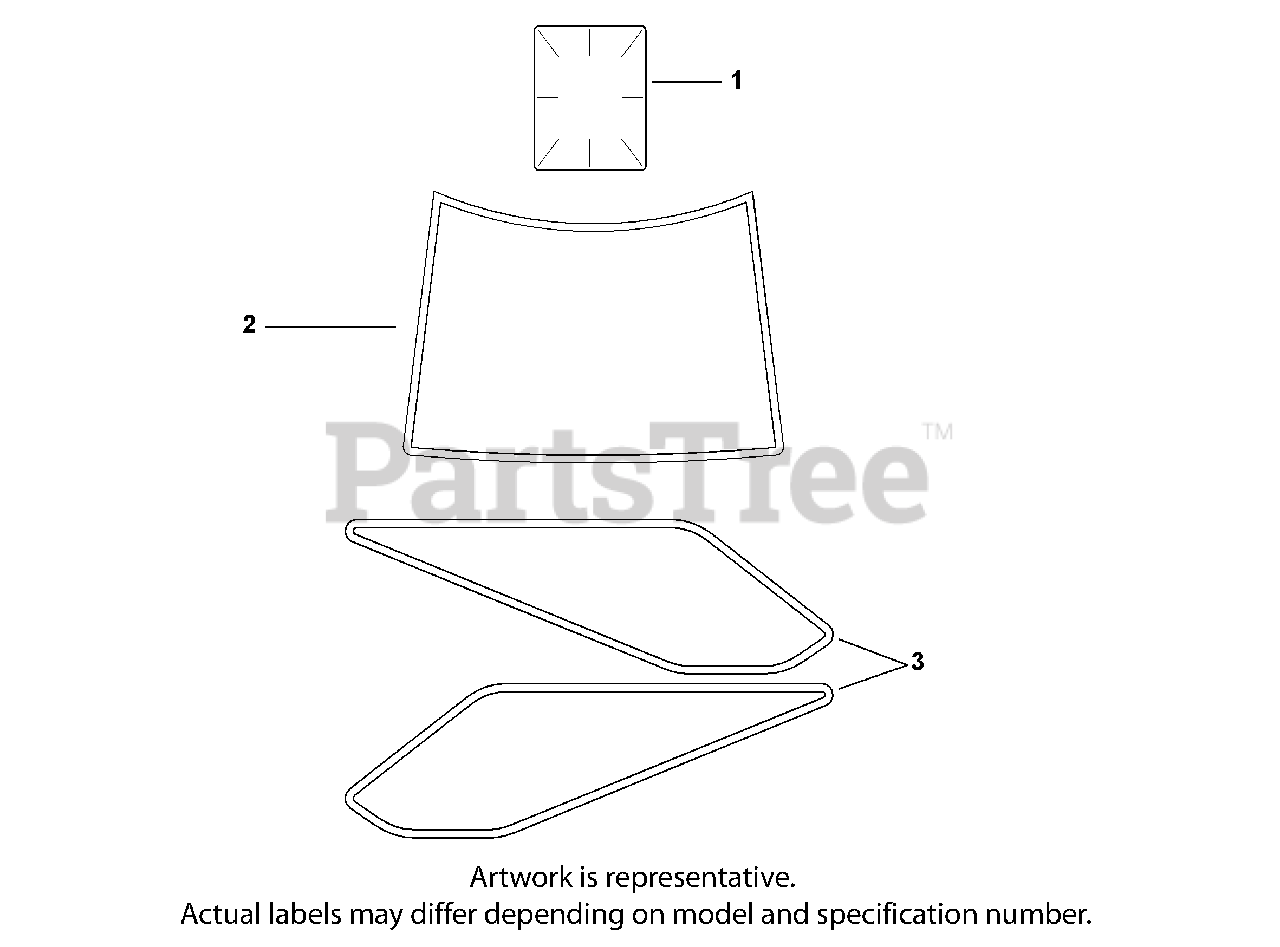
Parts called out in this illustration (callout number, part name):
1	Clear Laminate Decal
2	Decal, 22 HP
3	Decal, Twin Wings
